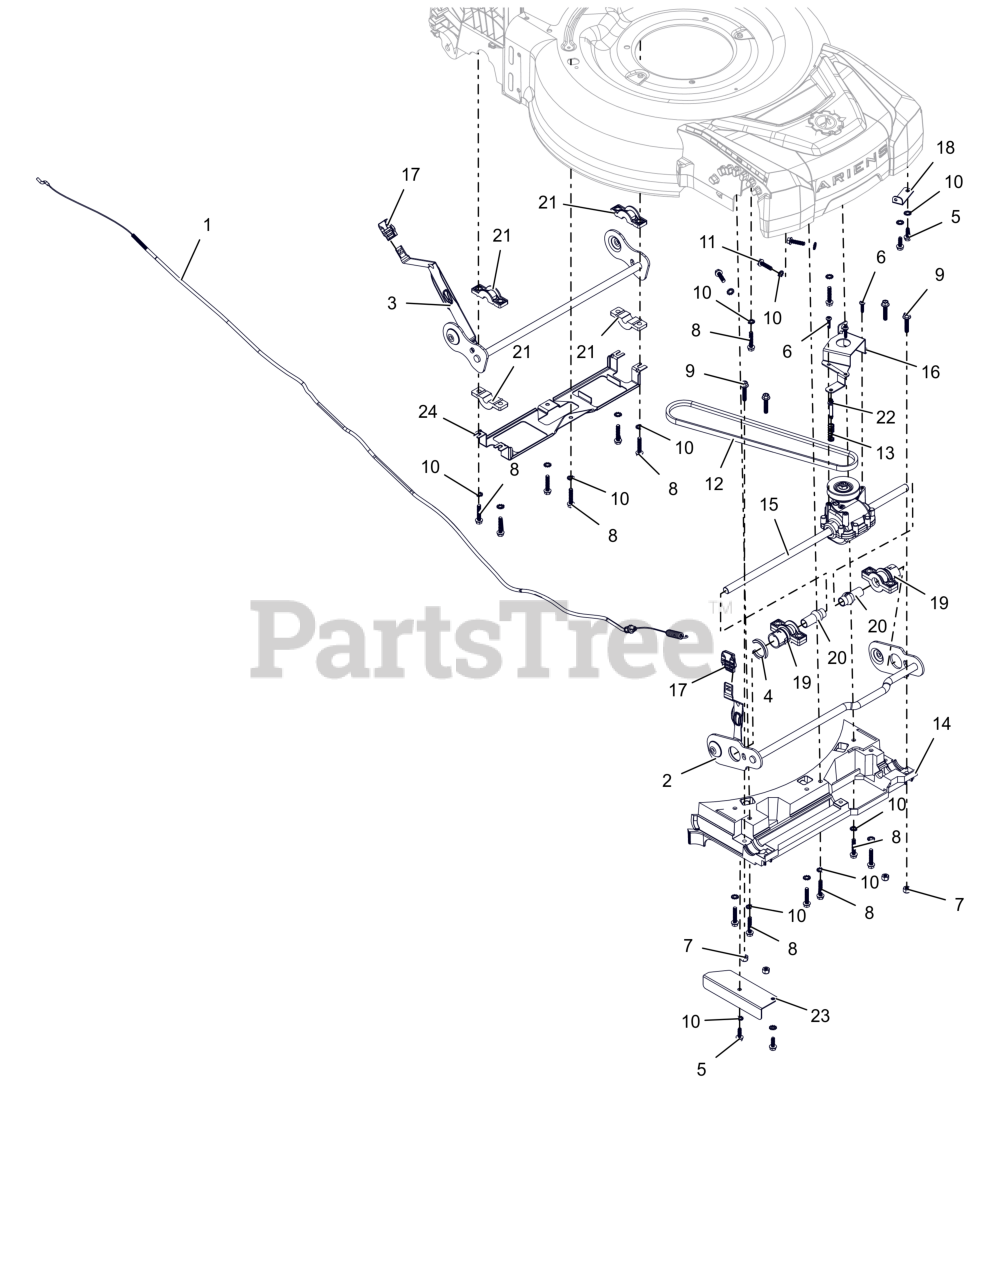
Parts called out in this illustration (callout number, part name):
1	CABLE, FWD TRANSMISSION
2	WLDMT, FRONT AXLE - SP (BLACK)
3	WLDMT, REAR AXLE - PUSH (BLACK)
4	CLIP, OUTER BUSHING
5	SCR, HI-LO HWH 1/4-15 X .750
6	SCR, TORX TRILOB PH 10-14X.75
7	NUT, NYLOC 1/4-20
8	SCR, HI-LO HWH 1/4-15 X 1.25
9	BLT, HWH 1/4-20 X 1.25
10	WSHR-LK-EXT, .256X.510X.028
11	SCR, HI-LO HWH 1/4-15 X 1.00
12	BELT, FWD
13	SPRG, ADJUSTER KNOB
14	TRAY, FRONT
15	ASM, FWD TRANSMISSION - MA 300
16	BRKT, FWD TRANSMISSION
17	GRIP, HOC
18	PLATE, CABLE ANCHOR (BLACK)
19	BUSHING, AXLE - OUTER
20	BUSHING, AXLE - INNER
21	BUSHING, SHAFT - HOC
22	HOLDER, RETURN SPRING
23	FLANGE, BLOW OUT (BLACK)
24	BRKT, RWD BACK SUPPORT (BLACK)
